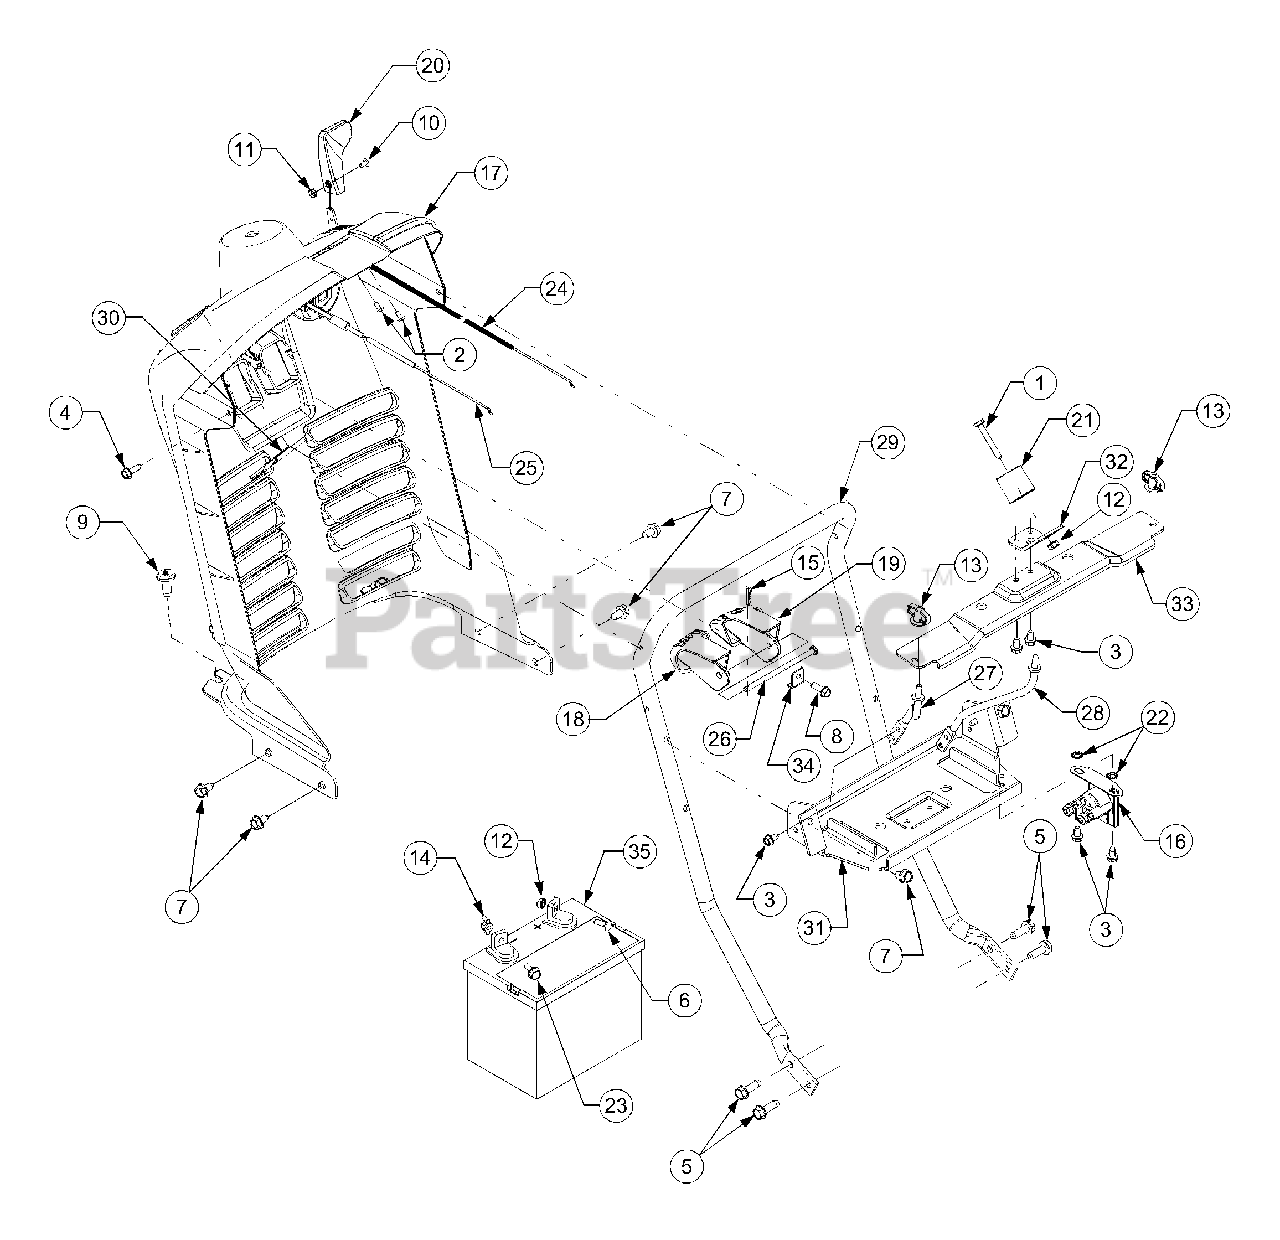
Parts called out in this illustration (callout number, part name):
1	Screw, 1/4-20, 1.75, Gr5
2	Screw, #10-24 X .375
3	Screw, Self-tapping, 1/4-20, 0.500
4	Screw, Hx. Wash. Hd, Tapp. 1/4-20 x .75
5	Screw, Hx. Wash. Hd, Tapp, 5/16-18, .875
6	Screw, Carriage, 1/4-20, .75,
7	Screw, Hx. Wash. Hd, Tapp, 5/16-12 x .75
8	Screw, 1/4-15, 0.750
9	Screw, Torx Hd. Tapp. 5/16-18 x .75
10	Screw, Machine, #8-32, 0.375, Trus Phillips
11	Nut, 8-32
12	Nut, Hex, 1/4-20, Sems
13	Nut, Wing, 1/4-20 w/ Bell Washer
14	Nut, Wing, 1/4-20
15	Internal Cotter Pin, .072 x 1.13
16	Solenoid, 12V, 100 Amp
18	Lever, Dash, Cruise
19	Lever, Dash, Brake
20	Knob, Throttle Control
21	Roller, Latch, Hood
22	Washer, External Lock, 1/4
23	Screw, Shoulder, 1/4-20, .25 x .15
24	Cable, Throttle, 38.0 Lg
25	Cable, Choke, 45.5 Lg.
26	Rod, .250 Dia x 4.25 Lg.
27	Rod, Support, Side Panel RH
28	Rod, Support, Side Panel LH
35	Battery, 275 CCA, Dry
